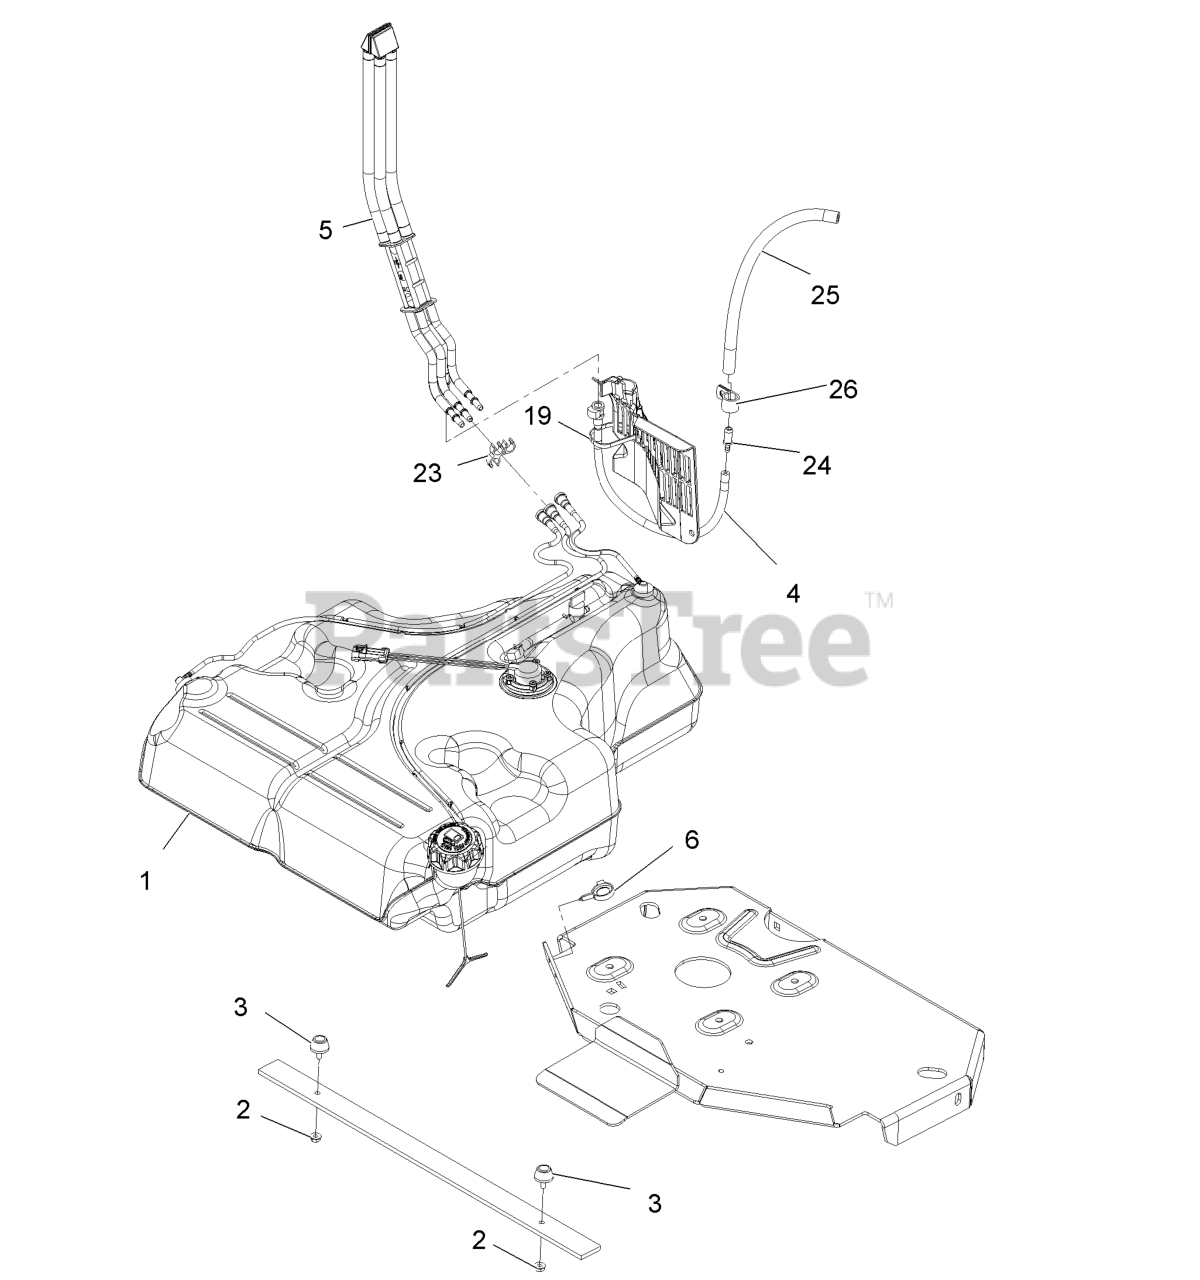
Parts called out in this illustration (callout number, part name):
3	BUMPER-RUBBER
4	HOSE ASM
5	FUEL MANIFOLD VENT ASM
6	CLAMP-HOSE
19	TIE-PLASTIC
23	CLIP-SPACER
24	FITTING-STRAIGHT
25	HOSE-FUEL
26	CLIP-LOOM
